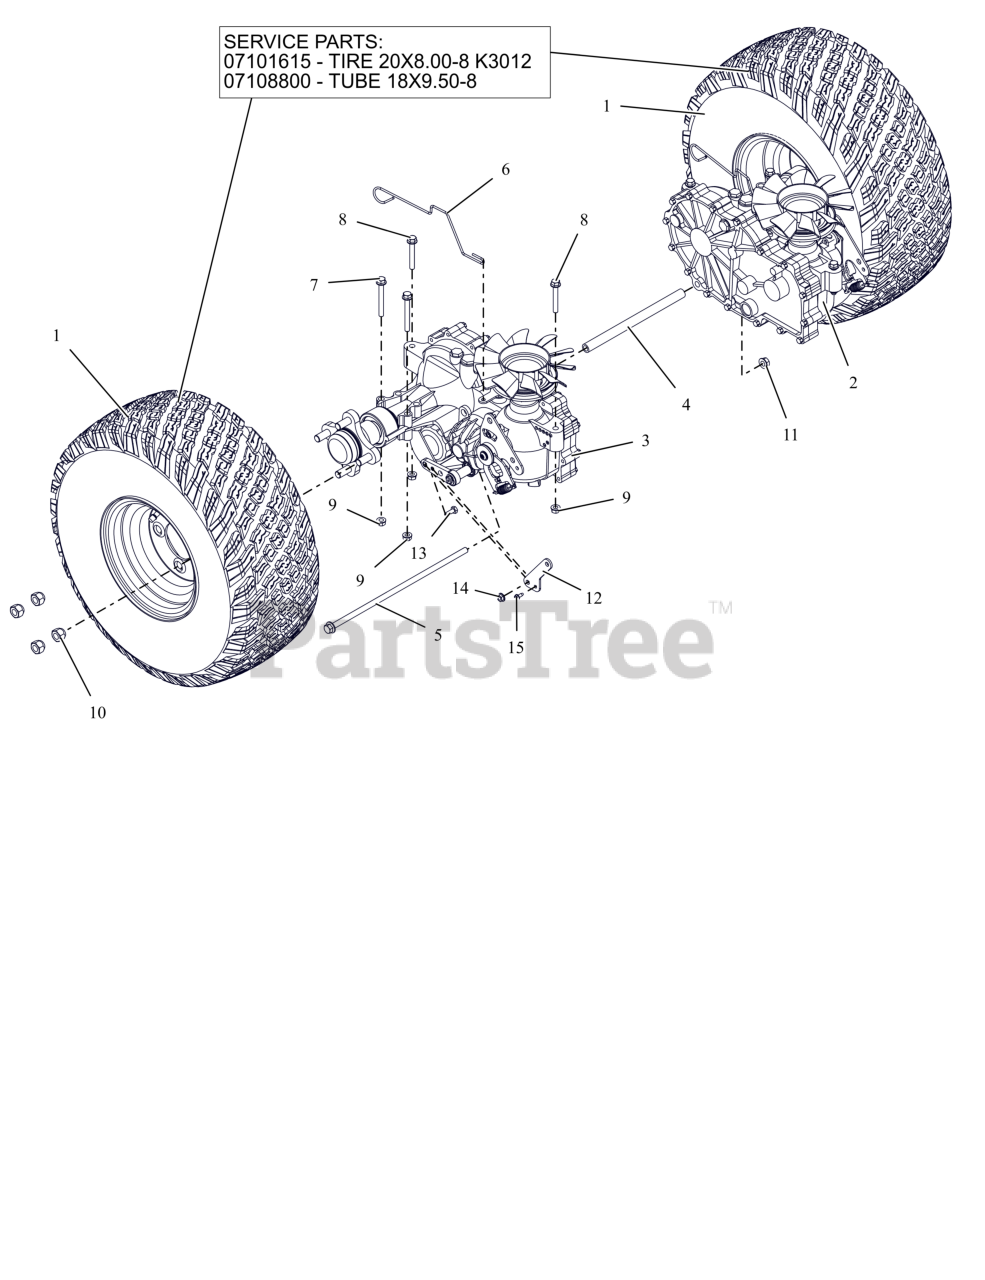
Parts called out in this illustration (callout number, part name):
1	ASM-WHL/TIRE 20X8.00-10 TURF
1	Tire, 20x8.00-8 K3012
1	TUBE 18X6.50/8.50/9.50-8/20X8.00/10.00-8
2	TRANSAXLE- 2800 - LH
3	TRANSAXLE- 2800 - RH
4	SPCR, TRANSAXLE .406 ID X .630 OD X 9.27 (BLACK)
5	BLT, HEX-FLG 0.375-16X13 GR5 ZC120
6	WIRE- DUMP VALVE LEVER
7	BLT,HEX-FLG .31-18X2.75 G5 ZCC
8	BLT,HEX-FLG .31-18X2.25 G5 ZCC
9	NUT,LK-CTR-FLG .31-18 GF ZCC
10	NUT, WHEEL .50-20 ZCC
11	NUT-LK-CTR-FLG .375-16 GF ZCC
12	PLATE- ADAPTOR PARKING BRAKE
13	BLT, HEX .25-20X.75 G5 ZCC
14	NUT-LK-CTR-FLG .25-20 ZC120
15	SCR,TAP #10-24X.50 HWH TR ZCC
